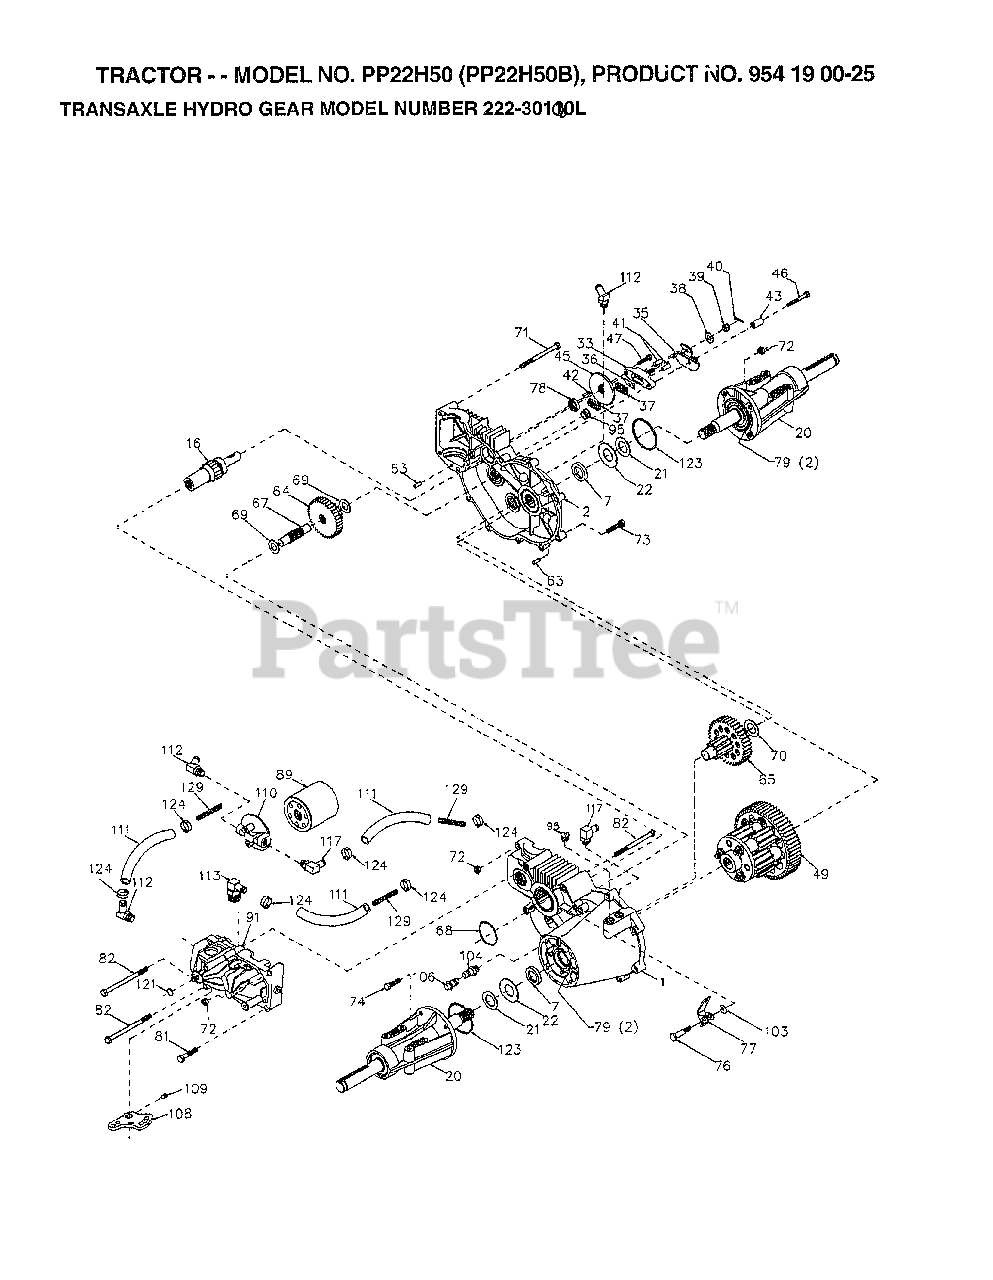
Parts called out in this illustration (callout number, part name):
1	HOUSING LH 70086
2	HOUSING RH 70088
7	SEAL.OIL.44782.HY
16	SHAFT BRAKE 62877
20	AXLE MTG 70087
21	WASHER 44805
22	WASHER 44806
33	YOKE.BRAKE.62589
35	ARM BRAKE 50214
36	PUCK PLATE 44134
37	PUCK BRAKE 44132
38	WASHER HYD 44130
41	PIN BRAKE 44127
42	KEY HI PRO 44143
43	SPACER 50259
45	DISC BRAKE 44090
46	BOLT 1/4-20 44276
47	BOLT 1/4-20 44433
49	DIFFRENTIAL.70251
63	PIN DOWL 44757
64	GEAR.14-38.44776
65	PINION DRIV 70051
67	SHAFT-44779
68	O RING 44781
69	WASHER 44795
70	WASHER 44794
71	BOLT 5/16 44827
72	LOCKNUT.43064
73	BOLT 5/16 44841
74	SCREW 5/16 45089
76	BOLT SHOULD 44785
77	ARM FREEWHL 44786
78	SEAL.OIL.44761
81	BOLT 5/16 43084
82	BOLT 5/16 44820
89	FILTER SPIN 50037
91	PUMP.BDU-10L-122
95	PLUG.9005110-5600
96	FITTING.SAE.50257
103	WASHER.50169
104	CAP.VENT.70109
106	O-RING.ASM.70110
108	ARM.CONTROL.45007
109	SCREW.SET.50018.
110	FILTER.HEAD.50207
111	HOSE.50632
112	FITTING.SAE.50604
113	FITTING.SAE.50592
117	FITTING.SAE.50589
123	O-RING.50405
124	CLAMP.50590
129	SPRING.LONG.50667
